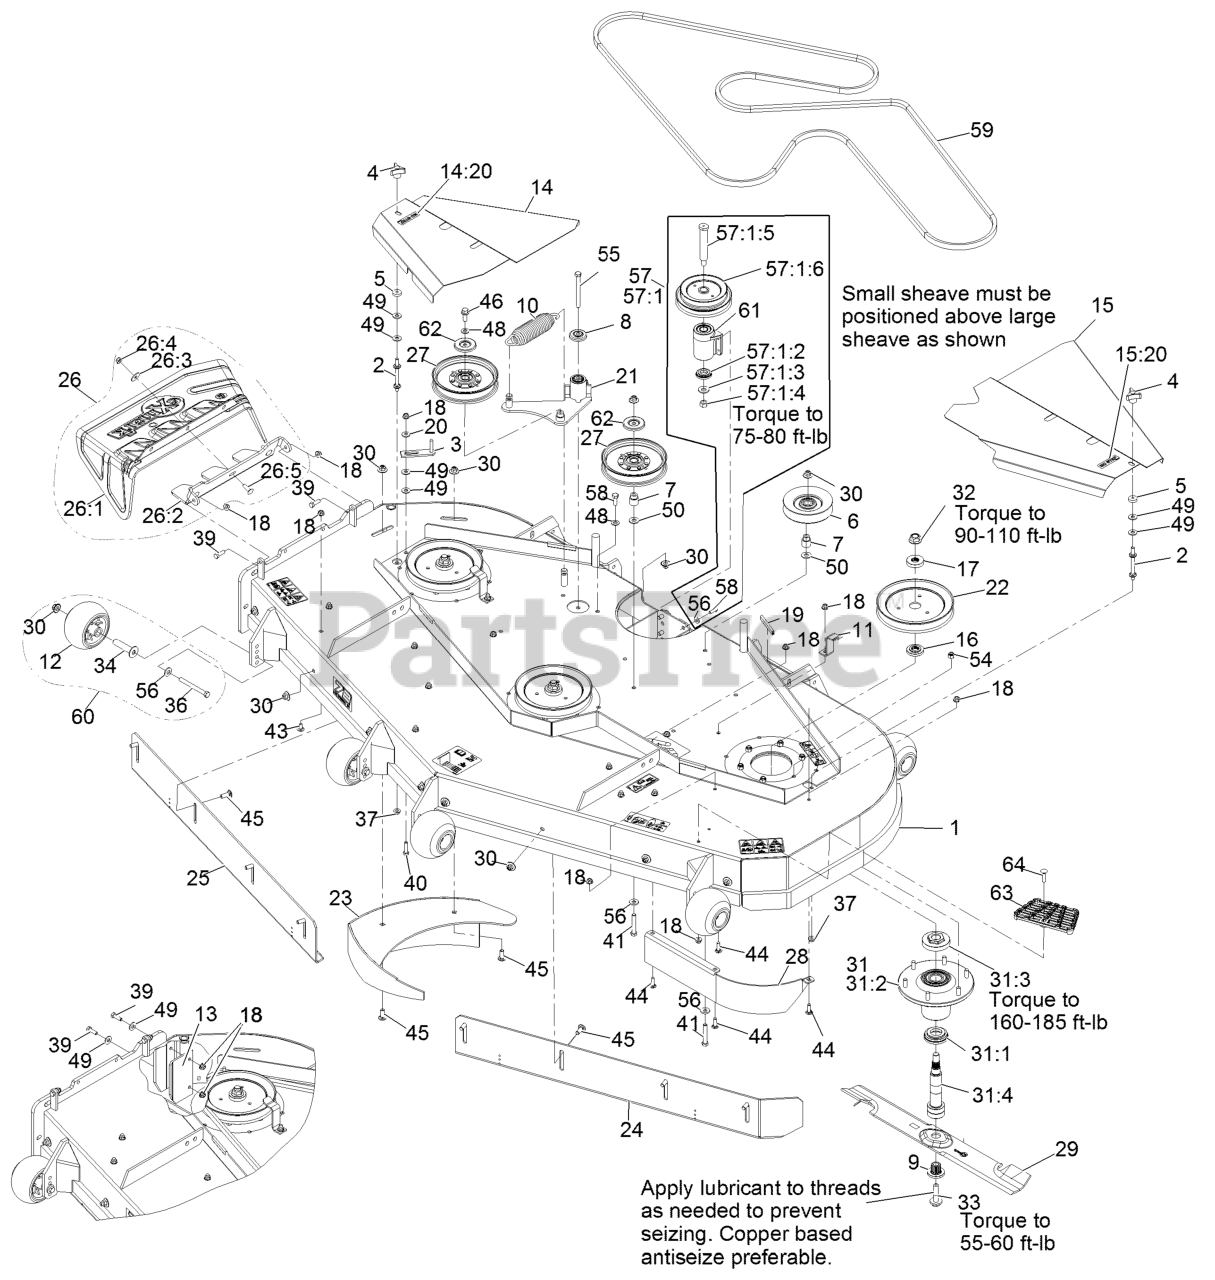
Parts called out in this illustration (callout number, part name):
1	ASM, DECK 725 W/DECALS
2	STUD-SHIELD, BELT (SHORT)
3	GUIDE-BELT
4	KNOB-3 PRONG
6	PULLEY-IDLER
7	BUSHING-IDLER
8	GUARD-TOP
9	BUSHING,SPLINED
10	SPRING-EXTENSION
11	LATCH,BELT SHIELD
12	ROLLER-SCALP, ANTI
13	DEFLECTOR,DISCHARGE
14	SHIELD, BELT RH 725 W/DEC
14:20	DECAL-NO STEP
15	SHIELD,BELT LH 725 W/DECA
15:20	DECAL-NO STEP
16	SPACER,SPLINED STEPPED
17	SPACER,SPLINED
18	NUT-HF, NI
19	STRIP-SEAL
20	WASHER-SPRING
21	KIT, IDLER ARM W/BEARINGS
22	SHEAVE,BLADE DRIVE 7.25
23	WLD,DOGLEG 725
24	WLD,BAFFLE FRT ADJ LH 725
25	WLD,BAFFLE FRT ADJ RH 725
26	ASM, DISCHARGE CHUTE
26:1	CHUTE,DISCHARGE LZ
26:2	HINGE,DISCHARGE CHUTE
26:3	WASHER-FLAT
26:4	NUT-HF, NI
26:5	SCREW-CARR
27	IDLER-PULLEY, FLAT 6.00X1
28	BAFFLE,SCROLL 725
30	Nut-Nyloc 3/8-16 Flg
31	ASM,SPINDLE HOUSING
31:1	GUARD,BOTTOM
31:2	ASM,CUTTER HOUSING
31:3	NUT, SPINDLE 7/8-14
31:4	SPINDLE,DOUBLE SPLINE
32	NUT-FLANGE, CENTERLOCK
33	SCREW,SEMS 1/2-20 X 2.19
34	AXLE, ROLLER
36	SCREW-HH 3/8-16 X 3 3/4 GR 8
39	SCREW-HH
40	SCREW-HH
41	SCREW-HH
43	SCREW-CARR
44	SCREW-CARR
45	SCREW-CARR
46	SCREW-HHF
48	WASHER-FLAT
49	WASHER-FLAT
50	WASHER-FLAT
54	NUT-LOCK, NI
55	SCREW-HH
56	WASHER-BELLEVILLE
57	KIT,JACKSHAFT 60/72-3750
57:1:2	SPACER-GUARD, BOTTOM
57:1:3	WASHER-SPRING
57:1:4	NUT-HEX
57:1:5	JACKSHAFT
57:1:6	SHEAVE, JACKSHAFT DOUBLE
58	SCREW-HH
59	BELT-V
60	KIT, ANTI-SCALP ROLLER
61	KIT, JACKSHAFT ASSY
62	SHIELD-DUST
63	STEP-DECK
64	Bolt-Carriage 5/16-18 X 1 1/4
